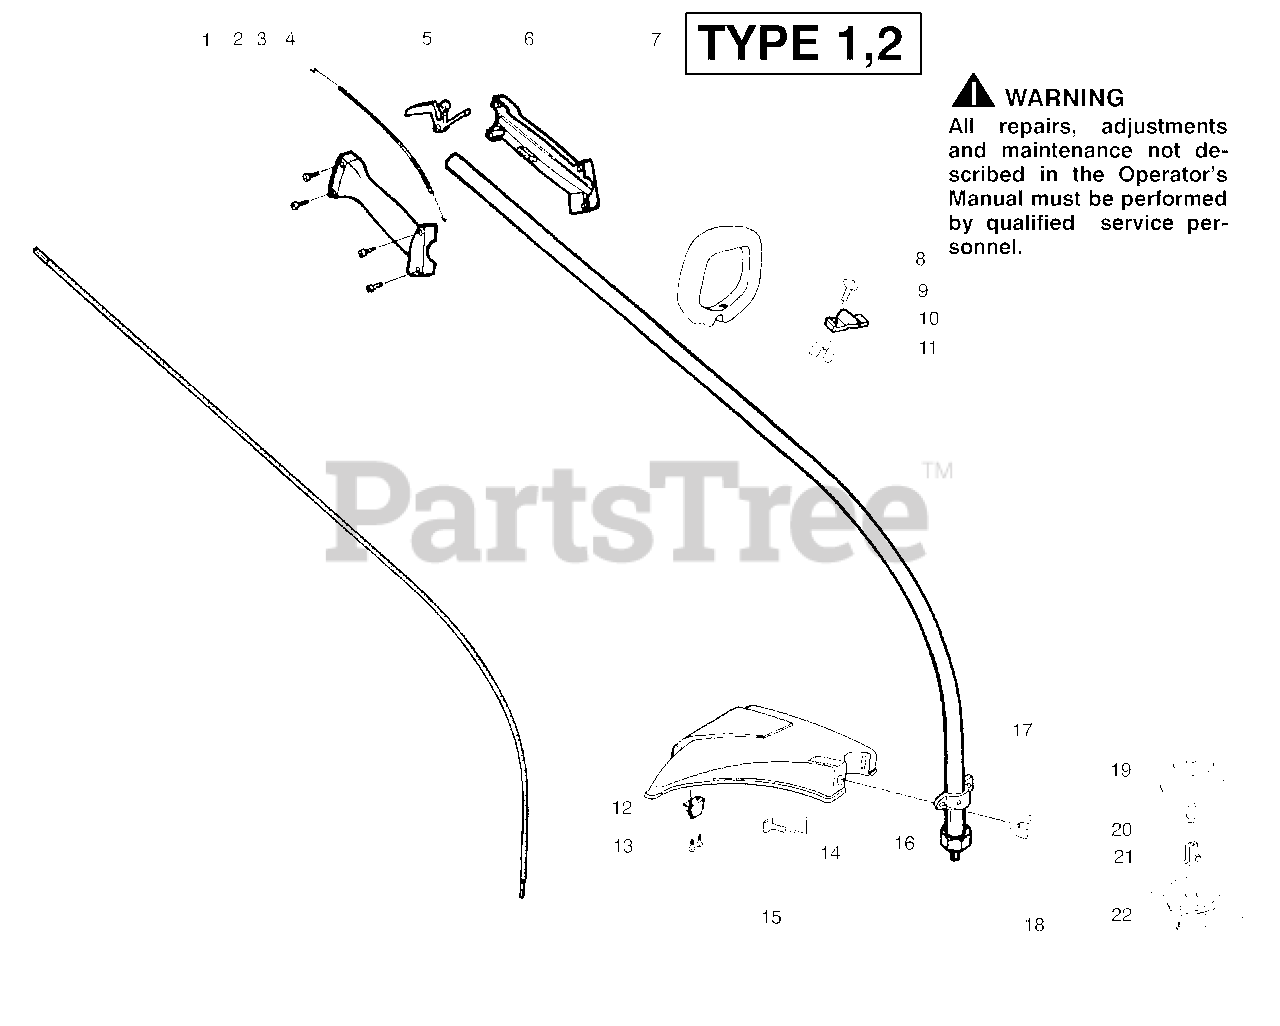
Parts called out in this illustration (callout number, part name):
1	Shaft-Flex
2	Throttle Hsg. (Right)
3	Screw-Throttle Hsg.
4	Assy-Throttle Cable
6	Throttle Hsg. (Left)
7	Assy-Drive Shaft Hsg.
8	Handle-Assist
9	Bolt-Handle/Shield
10	Clamp-Handle
11	Wingnut-Handle/Shield
12	Line Limiter
13	Screw-Line Limiter
14	Bolt-Handle/Shield
15	Kit-Shield Assy
16	Dust Cup
17	Wingnut-Handle/Shield
18	Accy-TNG VI Cutting Head
19	Assy-Hub
20	Spring-Compression
21	Clip-Retainer-Head
22	Accy- Spool w/Line
